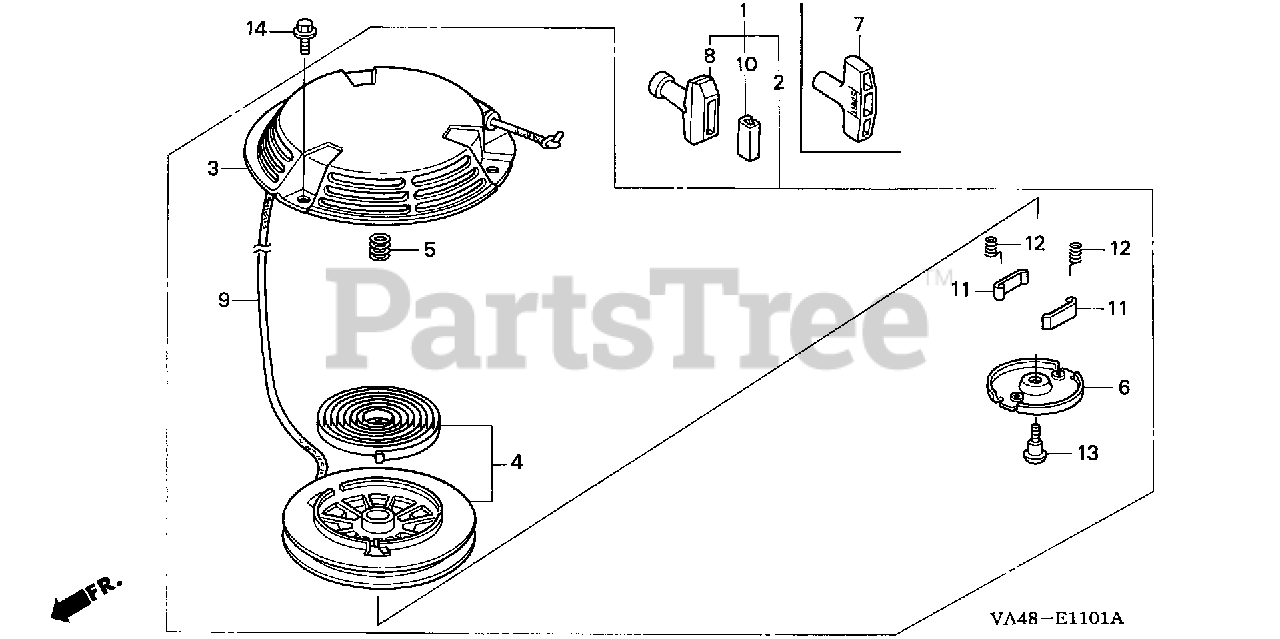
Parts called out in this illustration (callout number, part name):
1	STARTER ASSY., RECOIL
3	HOUSING ASSY.
4	PULLEY & SPRING ASSY.
5	SPRING, BRAKE (NOT AVAILABLE)
6	RETAINER (NOT AVAILABLE)
8	HANDLE
9	ROPE, LONG (55")
10	HANDLE, REINFORCEMENT
11	RATCHET, STARTER
12	SPRING, DOG
13	SCREW, CENTER (NOT AVAILABLE)
14	BOLT, FLANGE (6X8)
